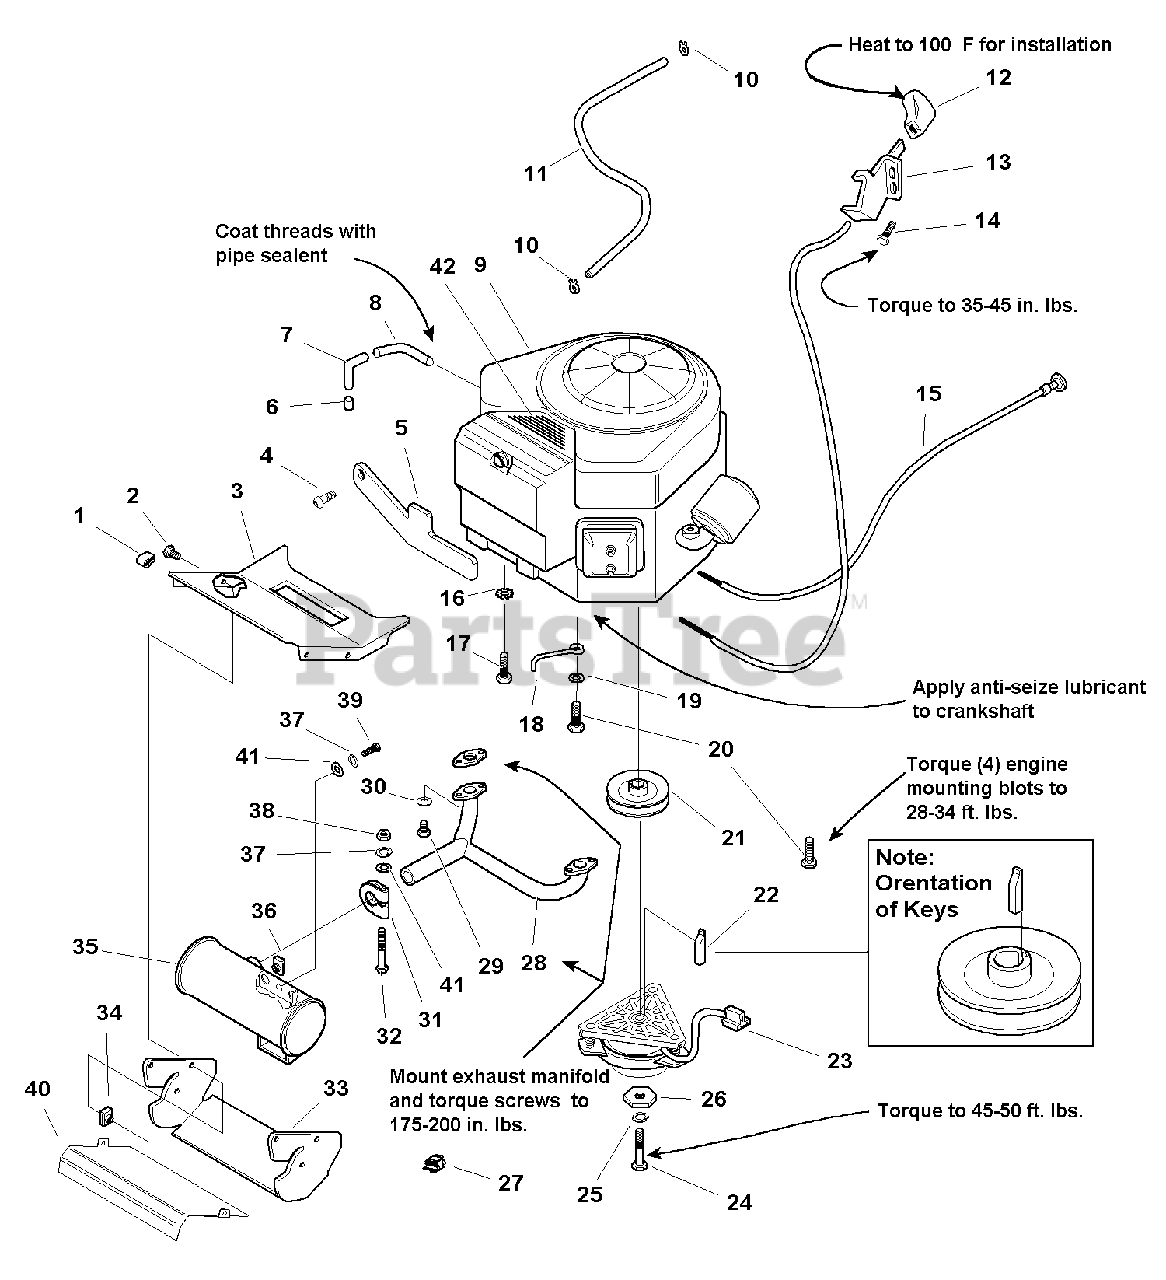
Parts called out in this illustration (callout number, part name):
1	CLIP, Speed Wire
2	CAPSCREW, Hex Flange Whizlock, 1/4-20 x 5/8
3	DUCT, Muffler, Top
4	CAPSCREW, Pan Head, Torx, #10-32 x 1/2 (Early Models)
5	BRACKET, Flat (Early Models)
6	CAP, Hex, 3/8-18NPT
7	FITTING, Pipe Elbow Street
8	PIPE, Oil Drain
9	ENGINE, 18.0HP Briggs & Stratton INTEK
10	CLAMP, Hose, 1/2 Diameter Type E
13	CONTROL, Throttle 3/16 Cable 35-3/4 Long, No Knob
13	CONTROL, Throttle 3/16 Cable 35-3/4 Long, No Knob (Export)
14	CAPSCREW, Hex Washer Head, 1/4 x 1/2
15	CONTROL, Choke 3/16 Cable 39-1/2 Long w/Knob
16	LOCKWASHER, External Tooth, 3/8
17	CAPSCREW, Hex Washer Head, Taptite, 3/8-16 x 1-1/2
19	WASHER, 3/8
20	CAPSCREW, Hex Washer Head, Taptite, 3/8-16 x 1-1/2
21	PULLEY & HUB ASSEMBLY
22	KEY, HI PRO, 1/4 x 2.000
23	CLUTCH, Electric
24	CAPSCREW, Hex Head, 7/16-20 x 2-1/2
25	LOCKWASHER, Spring, 7/16
26	WASHER, Hex
27	CLIP, Speed Wire
28	MANIFOLD, Exhaust
29	CAPSCREW, Hex Head, 5/16-18 x 3/4 G8
30	WASHER, 5/16
31	CLAMP, Exhaust
32	CARRIAGE BOLT, 5/16-18 x 2-3/4
33	DUCT, Muffler, Bottom
34	NUT, Speed, 1/4-20 Lug
36	NUT, Speed, 5/16-18 LUG
37	LOCKWASHER, Spring, 5/16
38	NUT, Hex, 5/16-18
39	CAPSCREW, Hex Head, 5/16-18 x 1.000
40	BAFFLE, Muffler
41	WASHER, 5/16
42	DECAL, 18HP Brigga & Stratton INTEK
